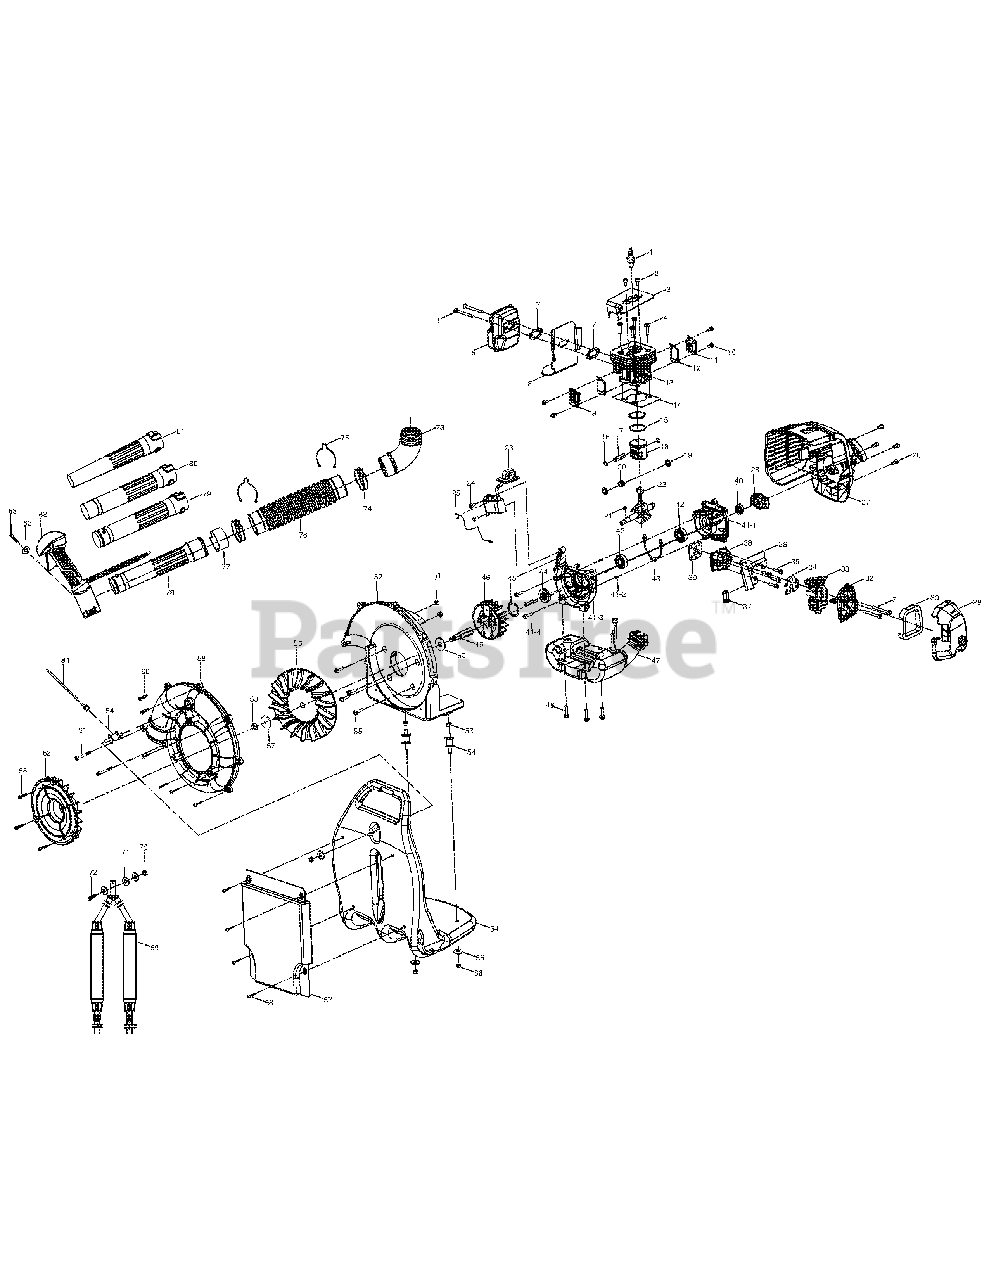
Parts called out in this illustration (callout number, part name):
1	SPARK PLUG
3	PLATE, SPARK SIDE
4	SCREW
6	MUFFLER ASS'Y
7	MUFFLER GASKET
8	MUFFLER PLATE
9	COVER, FLYWHEEL SIDE
11	COVER, STARTER SIDE
13	CYLINDER
15	PISTON RING
16	CIRCLIP
17	PISTON PIN
19	AXIS COVER
20	NEEDLE BEARING
22	CRANK/ROD ASS'Y
23	IGNITION COIL
24	SCREW
25	COIL WIRE
26	SCREW
27	STARTER HOUSING ASS'Y
28	PAWLS ASS'Y
29	FILTER ASS'Y
32	FILTER ASS'Y
33	CARBURETOR
34	CARBURETOR GASKET
35	SCREW
37	GROMMET
38	INSULATOR
39	INSULATOR GASKET
40	SEAL
41	CRANKCASE ASS'Y
41-1	CRANKCASE, STARTER SIDE
41-3	CRANKCASE, FLYWHEEL SIDE
41-4	SCREW
42	BEARING
43	GASKET, CRANKCASE SIDE
45	C RING
46	FLYWHEEL
47	FUEL TANK ASS'Y
48	SCREW
49	CONNECT AXIS
50	WASHER
51	NUT
52	SCREW HOUSING
53	NUT
54	VIBRO-ISOLATING RUBBER
56	IMPELLER
57	WASHER
58	NUT
59	SCREW HOUSING
60	SCREW
61	SCREW
63	SCREW
64	FRAME
67	CUSHION BACK
68	RIVET RIBBED
69	HARNESS
73	ELBOW PIPE
74	HOSEBEND
75	WIRE CLAMP
76	FLEX PIPE
77	ACTIVE RING
78	BASE PIPE
79	MIDDLE PIPE
80	END PIPE (56MM)
81	END PIPE (40MM)
82	THROTTLE LEVER ASS'Y
84	LIGATE TAPE
